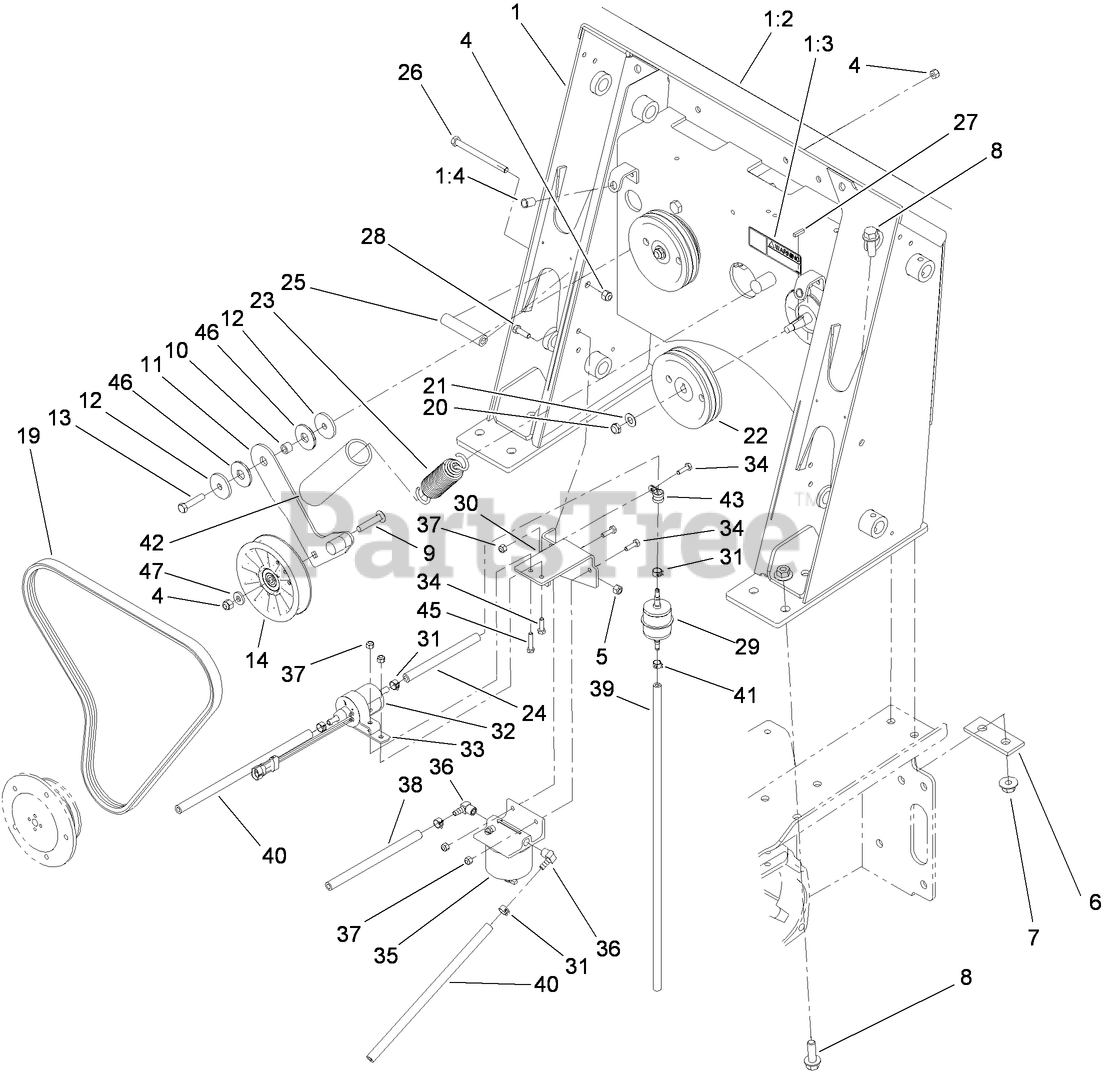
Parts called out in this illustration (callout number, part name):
1	LOADER TOWER ASM
1:2	DECAL-PANEL, CONTROL
1:3	DECAL-DANGER
1:4	INSERT-THREADED
4	NUT-LOCK, NI
5	NUT-LOCK, NI
6	PLATE-STIFFENER
7	NUT-LOCK, FLANGE
8	SCREW-HHF
9	BOLT-CARRIAGE
10	SPACER
11	IDLER ARM ASM
12	WASHER-PLAIN
13	SCREW-HH
14	PULLEY-IDLER
19	V-BELT
20	NUT-LOCK, NI
21	WASHER-FLAT
22	PULLEY
23	SPRING-EXTENSION
24	HOSE-FUEL
25	TUBE-SPACER
26	SCREW-HH
28	SCREW-HH
29	FILTER-INLINE
30	BRACKET-PUMP, FUEL
31	CLAMP-HOSE
32	PUMP-FUEL
33	BRACKET-PUMP, FUEL
34	SCREW-HH
35	SEPARATOR-FILTER / WATER
36	FITTING-ELBOW
37	NUT-LOCK, NI
38	HOSE-FUEL
39	HOSE-FUEL
40	HOSE-FUEL
41	CLAMP-HOSE
42	RETAINER-SPRING
43	CLAMP-R
45	SCREW-HH
46	WASHER-FRICTION, COMPOSITE
47	SPACER
